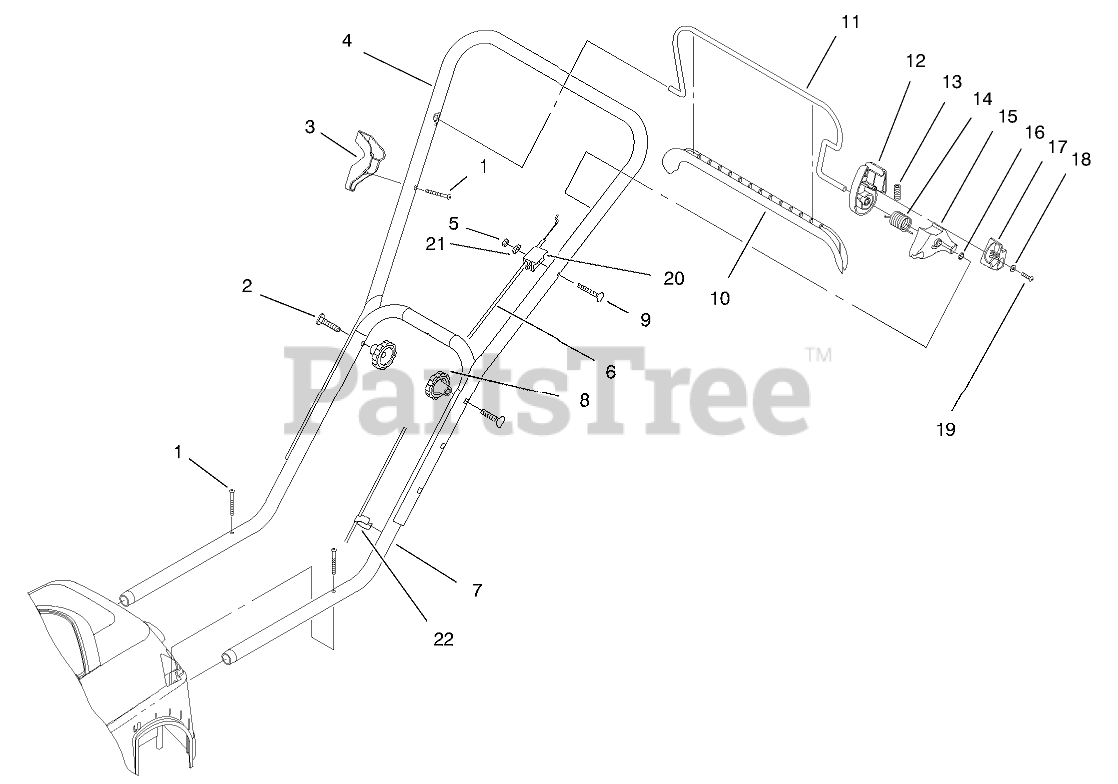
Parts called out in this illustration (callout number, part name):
1	SCREW-PPH
2	SCREW-HANDLE
3	LOCK - CORD
5	NUT-HEX
6	CABLE - CONTROL
9	SCREW-HANDLE
12	HOUSING - BAIL
13	SPRING - COMPRESSION
14	SPRING - BAIL
16	NUT - PUSH
17	SLIDE
18	WASHER - FLAT
19	SCREW-PPH
21	WASHER-FLAT
